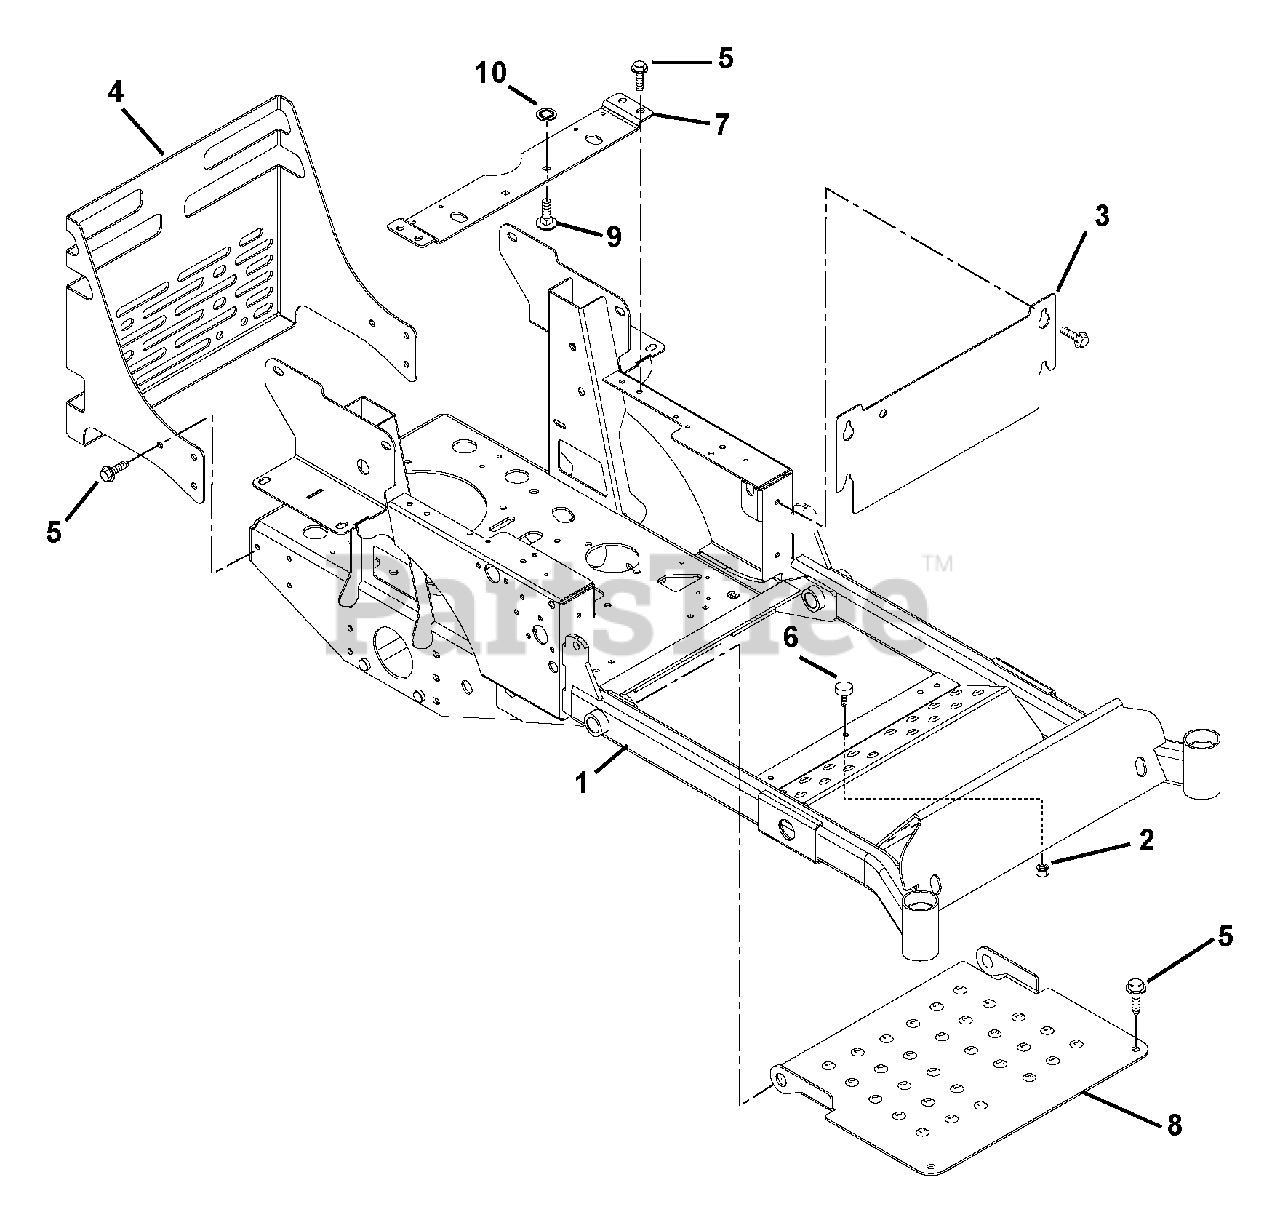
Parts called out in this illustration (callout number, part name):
1	Frame, Compact-Z
2	Nut, Spin Lock Flange .312-18
3	Access Panel
4	Bumper, Rear
5	Screw, Tapping .38-16 x .75 Hex Washer Head (056)
5	Screw, Tapping .38-16 x .75 Hex Washer Head (314)
6	Bumper, Rubber
7	Seat Support
8	Panel, Inspection
9	Bolt, Round Head Square Short Neck .31-18 x .74 Grade 5
10	Nut, Push .312
